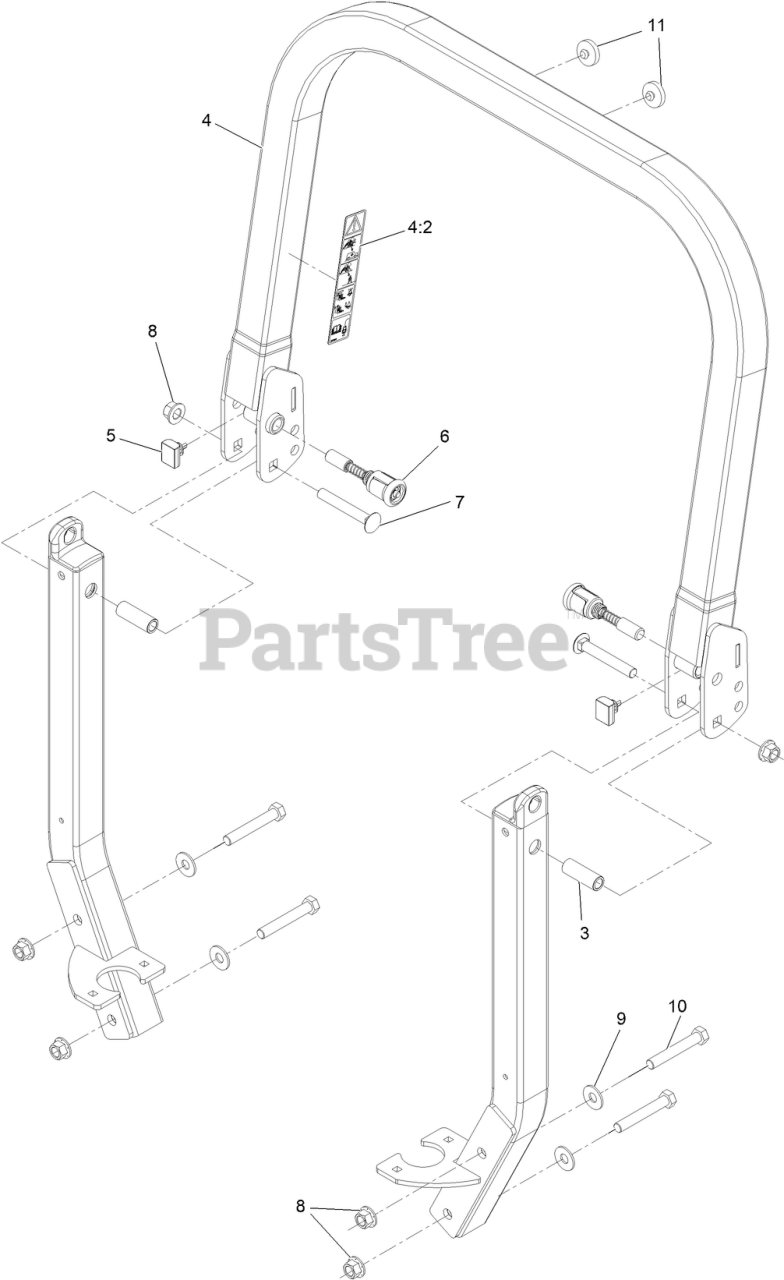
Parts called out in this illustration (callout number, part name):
4	UPPER ROPS ASM
4:2	DECAL-WARNING
5	BUMPER-ROPS
6	PIN-SPRING
7	SCREW-CARR
8	Nut-Lock 1/2-13
9	WASHER-SPRING
10	SCREW-HH
11	BUMPER-PUSH-IN, RUBBER
